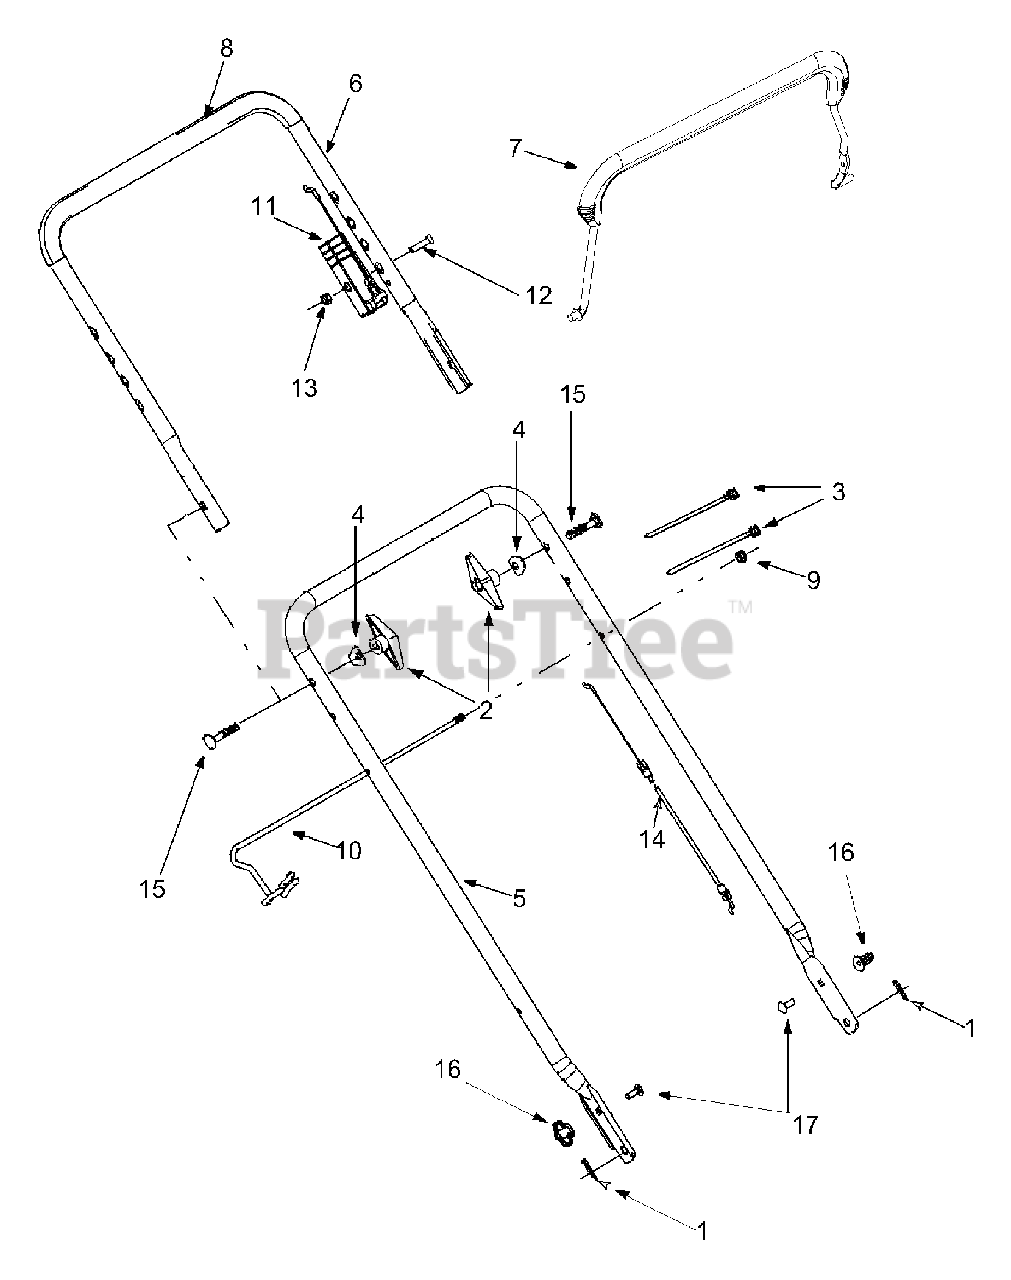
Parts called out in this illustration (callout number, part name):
1	Hairpin Clip
2	Wing knob
3	Cable Tie
4	Saddle Washer
8	Foam Grip
9	Hex Nut, 5/16-18
11	Housing Control
12	Oval C-Sunk Scr.
13	Hex L-Nut 1/4-20 Thd.
14	Control Cable, 46"
15	Carriage Bolt
16	Knob, Wing, 1/4-20
17	Carriage Screw, 1/4-20 x .75
